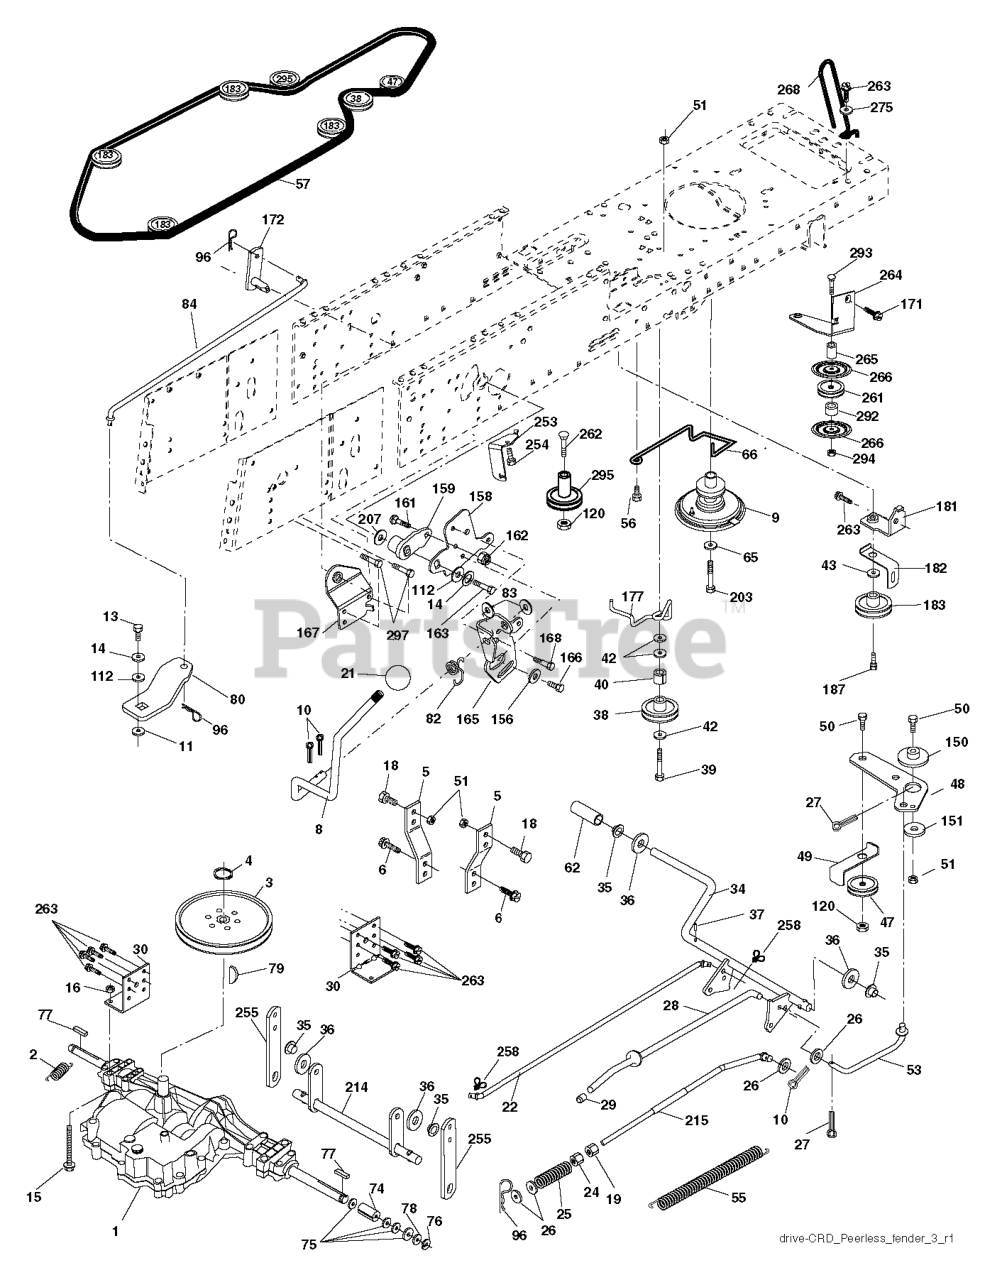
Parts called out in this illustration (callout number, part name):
2	SPRING,BRAKE RETURN
3	PULLEY
4	RETAINING RING LT
5	STRAP TORQUE
6	SCREW 5/16"
8	ROD SHIFT FENDER ADJUST LT
10	PIN COTTER
11	WASH-SHFT PLT LT
13	BOLT 1/4-28X3/4
14	LOCKWASHER
15	BOLT HEX 5/16-18 GR 5
16	NUT.71038.31-18.HEX.NYLOCK
19	NUT
21	KNOB T (1/2-HOLE)
22	ROD
24	NUT
25	SPRING ROD LT
26	WASHER
27	COTTER PIN
28	ROD, PARKING BRAKE
29	PLUNGER CAP
30	BRKT, MOUNT TRNSAXLE
34	SHAFT, FOOT PEDAL
35	BEARING.NYLON
37	DRIVE PIN
38	PULLEY.FLAT
42	WASHER
47	IDLER PULLEY
48	BELLCRANK, CLUTCH
49	RETAIN BELT
50	BOLT.3/8-16X1.50
53	LINK.CLUTCH.7.66.2005
55	SPRING, RETURN LT
56	SCREW.3/8-16
57	V-BELT.KEV.111"
62	PEDAL COVER T
65	LOCKWASHER
66	KEEPER BELT ENGINE
74	SPACER AXLE
77	SQUARE KEY
79	KEY STD (1373) DANA
82	SHIFT SPRING
83	WASHER
96	RETAINER M
120	NUT LOCK FLG 3/8-16 UNC
150	BUSHING.BELLCRANK.GRD.DR
151	WASHER 12/32X2X10GA
156	WASHER.SRRTD.5/16
158	BRACKET
159	RB HUB.SHIFT
161	BOLT
162	NUT.CROWNLOCK.1/4
165	RP BRACKET
166	CAPSCREW.HXHD.FLG.5/16-18X.625
167	BRACKET.SUPT.SHIFT.CRD
168	BOLT.SHOULDER.5/16-18X
172	SHAFT
181	BRACKET
182	BELT GUIDE
183	PULLEY.V-IDLER.
187	BOLT.5/16-18X1.25
203	BOLT.HEX.7/16-20 X 5
207	WASHER NYL
214	LEVER
254	SCREW 3/8-16X1
255	SHAFT
258	CLIP RETAINER
261	FLAT IDLER PULLEY
263	SCREW, 3/8-16X3/4
264	BRACKET.IDLER.CHASS.NORAM.2010
266	PROTECTOR
268	GUARD MUFFLER
275	WASHER
292	SPACER
293	BOLT.RDHD SQNK 3/8-16 X 3-1/2
294	NUT.HEX.3/8-16
295	PULLEY IDLER COMPOSITE
297	SCREW LT.3/8-46X5/8
